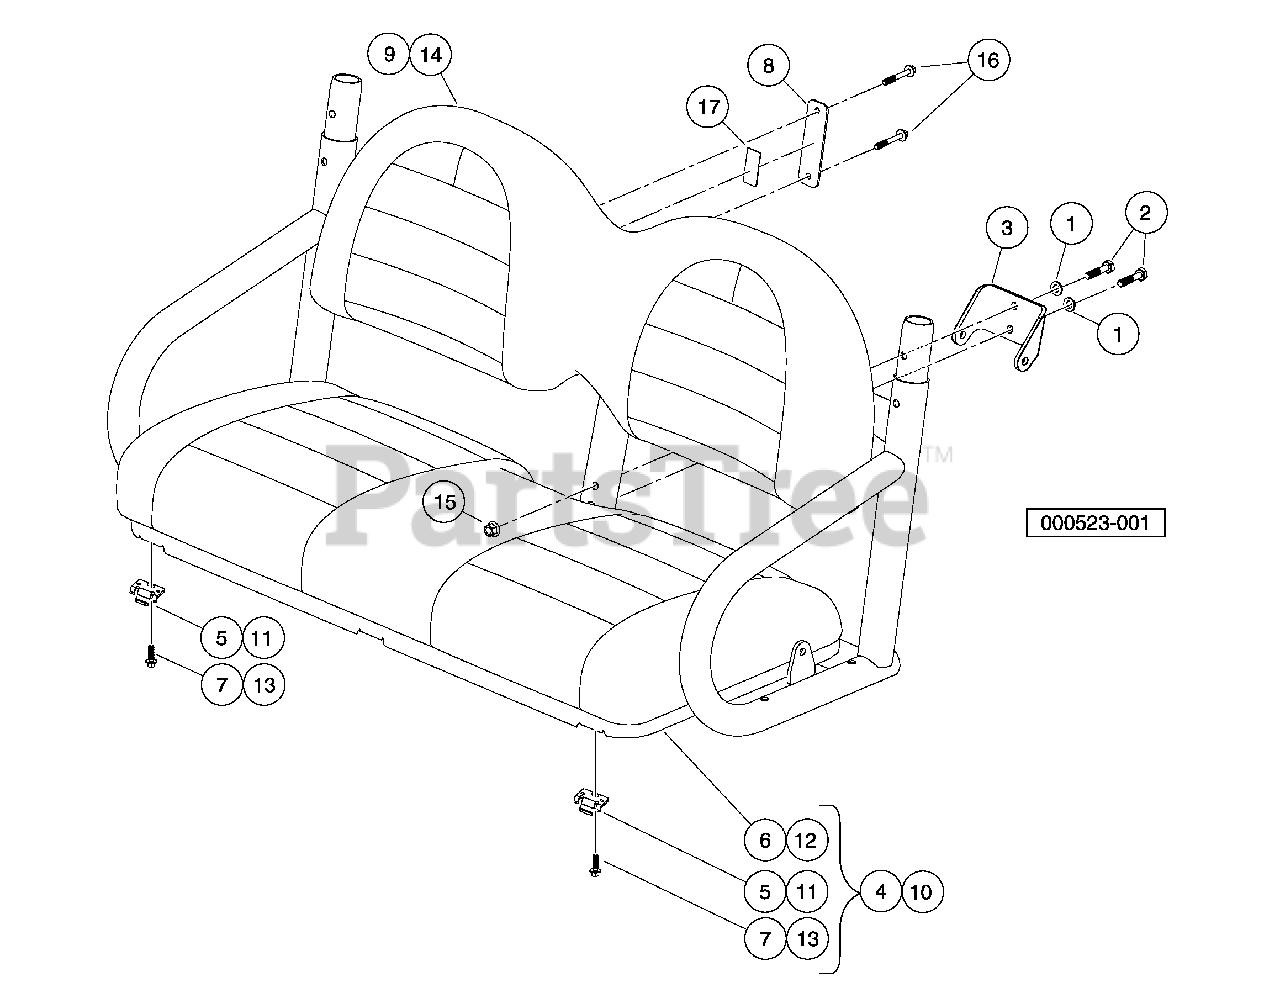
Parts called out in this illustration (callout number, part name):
1	Washer, Hard, M10, Zn-Ni/Blk
2	Bolt, M10 X 45, Zn-Ni
3	Bracket, Seat Belt, Bench
4	Asm, Seat Bottom, Bench, Gray
5	Hinge Plate
6	Asm, Seat Bottom, Bench
7	Bolt Flg Blk, M8 X 25, Loctite
8	Bracket, Seat Back, AWD
9	Seat Back, Bench, Gray
10	Asm, Seat Bottom, Bench, Black
11	Hinge Plate
12	Seat Bottom, Bench, Black
13	Bolt Flg Blk, M8 X 25, Loctite
14	Seat Back, Bench, Black
15	Nut, Flanged, M10 x 1.5, Black
16	Bolt Flg Blk, M8 X 55, Loctite
